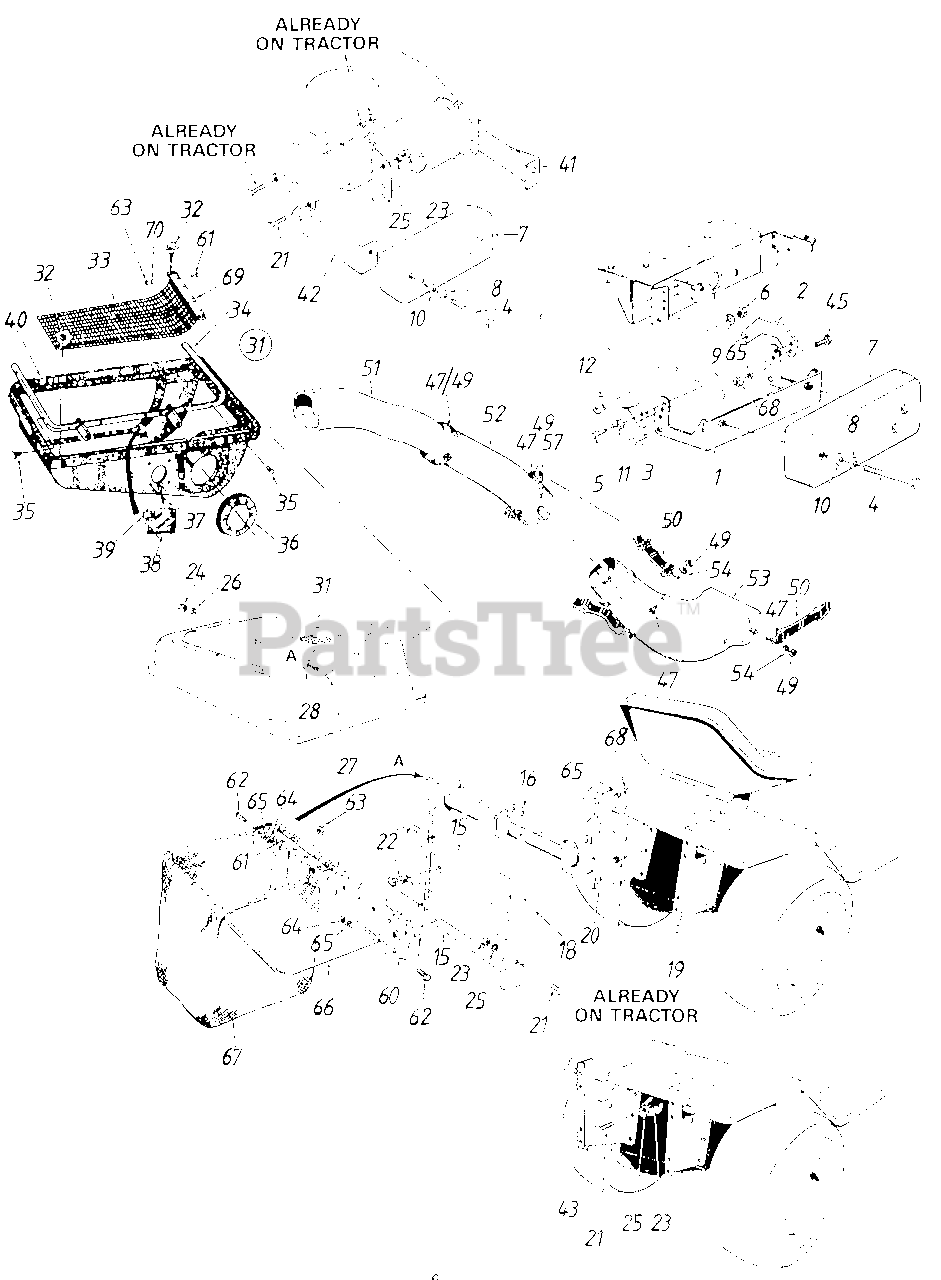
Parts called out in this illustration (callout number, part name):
1	Weight Brkt. Ass'y.
2	Weight Brkt. Tie Strap L.H.
3	Hex Bolt 7/16-20 x 1.0" Lg.
4	Hex Bolt 3/8-16 x 4.5" Lg.
5	Hex AB Tap Scr. 5/16-18 x 1.0"
6	Hex Jam Nut 7/16-20 Thd.
7	Front Counter Weight 38 lbs.
8	Bell.-Wash. 400" I.D. x .88" O.D.
9	L.-Wash. 7/16" I.D.
10	Fl.-Wash. .390" I.D. x 1.12" O.D.
11	Spacer
12	Weight Brkt. Tie Strap-R.H.
15	Catcher Support Tube Mtg. Brkt
16	Catcher Support Tube Ass'y.
18	Catcher Latch and Support Brkt.
19	Grass Catcher Support Brkt-R.H.
20	Grass Catcher Support Brkt.-LH.
21	Hex Bolt 5/16-18 x .75" Lg.
22	Hex Bolt 1/4-20 x .62" Lg.-Grade 5
23	Hex Nut 5/16-18 Thd.*
24	Hex Nut 3/8-16 Thd.*
25	L.-Wash. 5/16" I.D.*
26	L.-Wash. 3/8" I.D.*
27	Shld. Bolt 3/8-16 x .500" Dia.
28	Bell.-Wash. .505" I.D. x 1.00" O.D.
31	Grass Catcher Cover Ass'y.
32	Twist Fastener
35	Hex Tap Scr. 1/4-20 x .5" N Lg.
36	Seal
37	Truss Mach. B-Tap Scr. #10 x .5" Lg.
38	Plastic Plate
39	Speed Nut
40	Grass Catcher Cover
41	Weight Brkt. Ass'y.-N L.H.
42	Weight Brkt. Ass'y.-N-R.H.
43	Grass Catcher Support Brkt
45	Hex Bolt 1/4-20 x .88" Lg.
47	Hex Bolt 1/4-20 x .50" Lg.
49	Hex Ins. L.-Nut 1/4-20 Thd.
50	Retainer Strap Ass'y.
51	Catcher Elbow
52	Catcher Tube
53	Discharge Chute
54	L.-Wash. .270" I.D. x .57" O.D.
57	Retainer Hook Brkt.
61	Truss Mach. Scr. #10-24 x .50" Lg.
62	Hex Bolt 1/4-28 x .75" Lg.
63	Hex Sems Nut #10-24 Thd.
64	Hex Nut 1/4-28 Thd.*
65	L.-Wash. 1/4" I.D.*
67	Grass Catcher Bag
68	Hex Nut 1/4-20 Thd.*
69	Screen Mtg. Brkt.
70	Flat Wash. 1/4" I.D.
